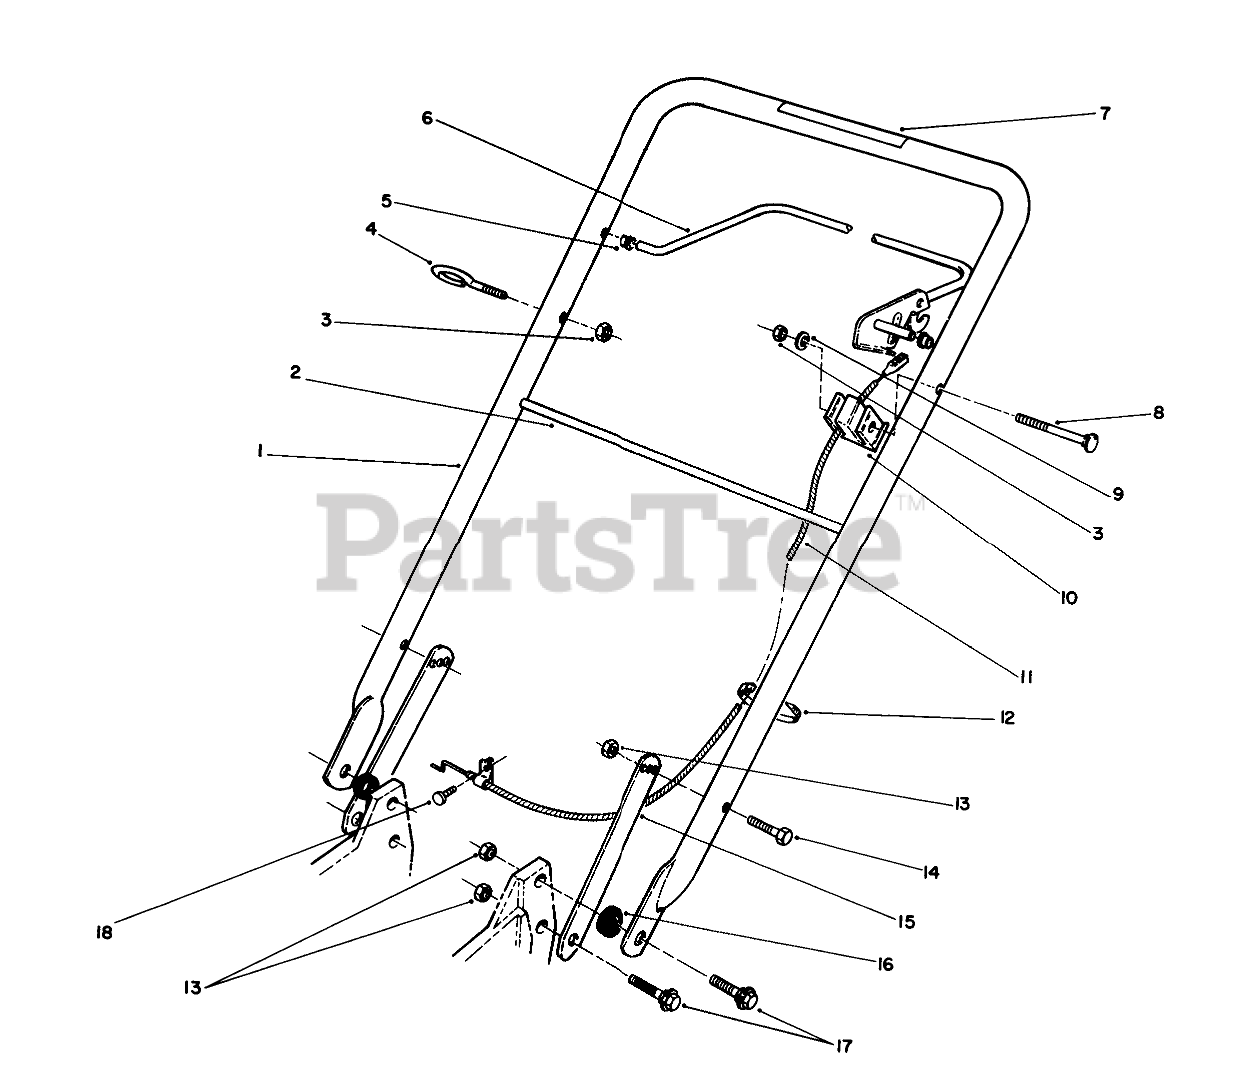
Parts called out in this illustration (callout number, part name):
1	Handle (Incl. Ref. #7)
2	B ROD - BAG
3	NUT-LOCK, NI
4	BOLT-EYE
5	Bushing-Nyliner
6	CONTROL BAR WA
7	Decal-Warning
8	SCREW-HH
9	WASHER-FLAT
10	SUPPORT-CABLE
11	BRAKE CABLE
12	TIE-CABLE
13	NUT-LOCK, NI
14	SCREW-HH
15	HANDLE LATCH
16	SPACER-PIN, MOUNTING
17	SCREW-HH
18	SCREW-HH
